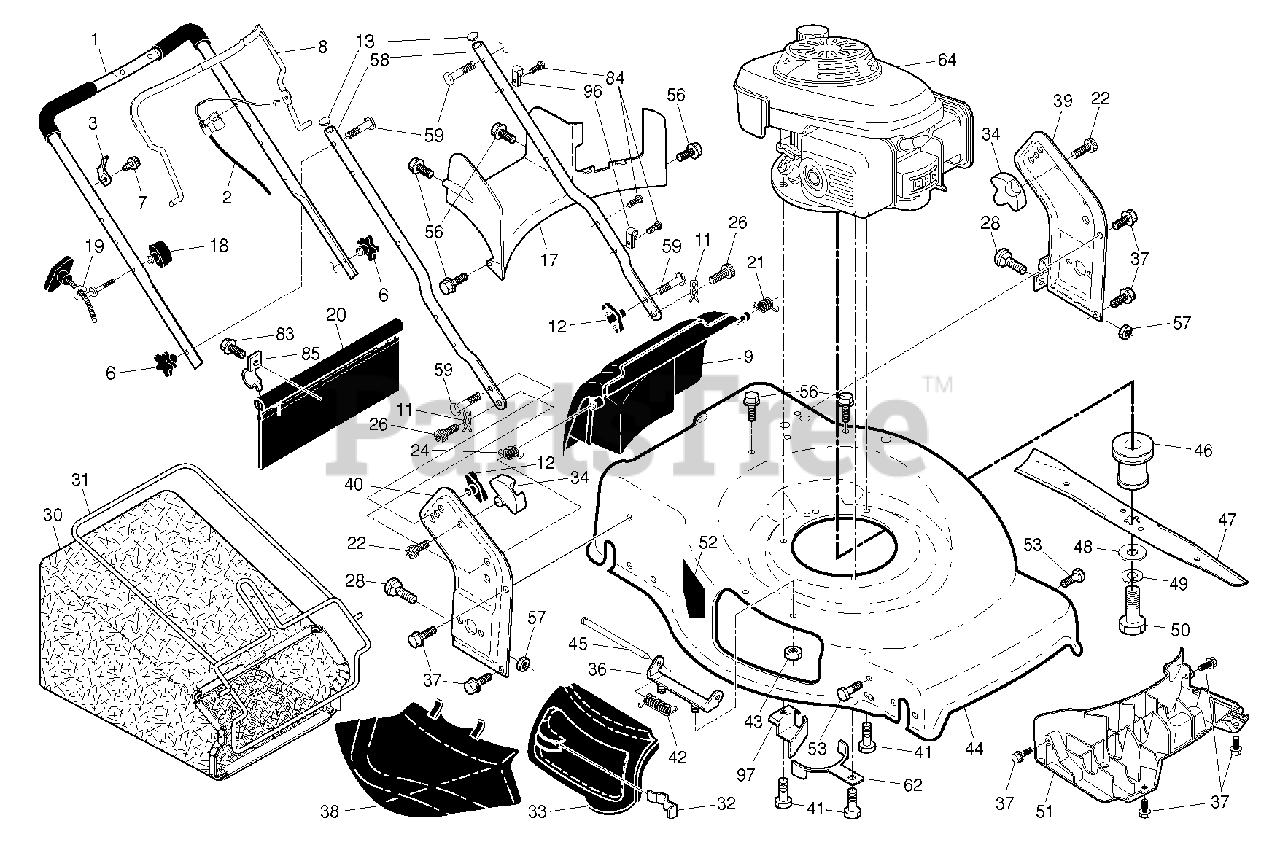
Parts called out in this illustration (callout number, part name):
1	HANDLE.ASM.UP.BLK.W/GRIP
2	CABLE.MZR.ZONE.CONTROL
3	BRACKET.UPSTOP.RT
6	KNOB.HANDLE.PLASTIC.STAR.BLACK
8	BAIL.MZR.EZ2.DSTR.22+.BLACK
11	COTTER.HAIRPIN.DOOR/HANDLE.PIV
13	PLUG.PLASTIC.7/8".14-20.GAUGE
17	BAFFLE.REAR.22+RGD.AWD.PLASTIC
18	T-KNOB.NEW ROPE GUIDE
19	GUIDE.ROPE.BLK.ZINC.CHROM
20	SKIRT.REAR.22PLUS.RGD.LW.2012
21	SPRING.LH.GRAY
22	SCREW.PAN.HEAD.#10
24	SPRING.RH.GRAY
26	SCREW,DOOR/HANDLE.PIVOT
30	GBAG.A1640010.BLACK.GENERIC
32	LATCH.DOOR.ZINC
33	DOOR.MULCH.22.BLACK.MULTI-BRAN
34	BRACKET.GRASSBAG.ATTACHING.BLK
36	BRACKET.ASM.HINGE.21.FWGD.
37	BOLT.5/16HEX.WHS.HD
38	DEFLECTOR.CLIPPING.22.BLACK
39	BRACKET.ASM.HANDLE.LT.22+.BLAC
40	BRACKET.ASM.HANDLE.RT.22+.BLAC
41	BOLT 3/8-16X1-1/8
42	SPRING.TORSION
43	NUT.HEX.FLANGE.1/4
44	HOUSING.22+.RGD.MC.WO.SP.BLUE
45	ROD.HINGE.21
46	ADAPTER.BLADE.25MM.3MPH
47	BLADE.22+.PREMIUM/PREC.FGD/RGD
48	WASHER,HARDEN
50	SCREW, HEX HD 3/8-24 X 1-3/8
51	BAFFLE.FRONT.22.PLUS
53	BOLT.5/16HEX.WHS.HD
56	SCREW.HX.13X.750
57	NUT.FLANGE.5/16
58	HANDLE.LOWER.22+BT.2PC.BLK
59	BOLT, HANDLE 5/16-18X1.75
62	BRACKET.BELT.GUIDE.22+.BZP
83	TAPPING SCREW
84	FASTENER.PUSH.O.250X0.783
85	BRACKET.SKIRT.22+.BZP
96	CLIP.CABLE.BLK
97	BRACKET.DRIVE.COVER.RGD.
